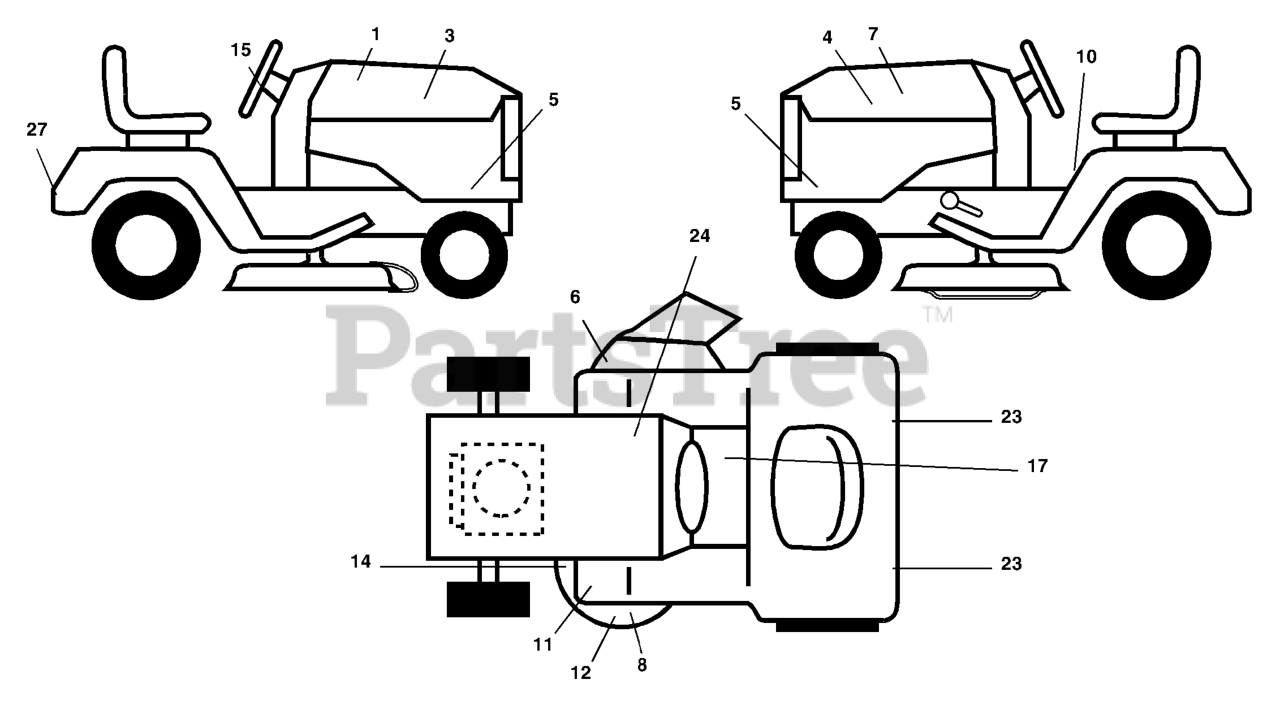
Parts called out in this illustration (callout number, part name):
1	DECAL.RPL.GTH2548
6	DECAL.WARN.KEEP.HAND.AWAY
7	DECAL HOOD CUST. RESP.
8	DECAL, MOWER HEAVY DUTY
10	DECAL FENDER DANGER
11	DECAL, FOOTREST
12	DECAL CLUTCH/BRAKE
14	DECAL V-BELT SCHEMATIC
15	DECAL.STEERING.HUSQ.BLUE
17	DECAL, SADDLE BRAKE PARKING
23	REFLECTOR-TAIL YT
24	DECAL BTRY SYMBOLS
27	DECAL.BYPASS.FENDER.CRD.LT.YT
